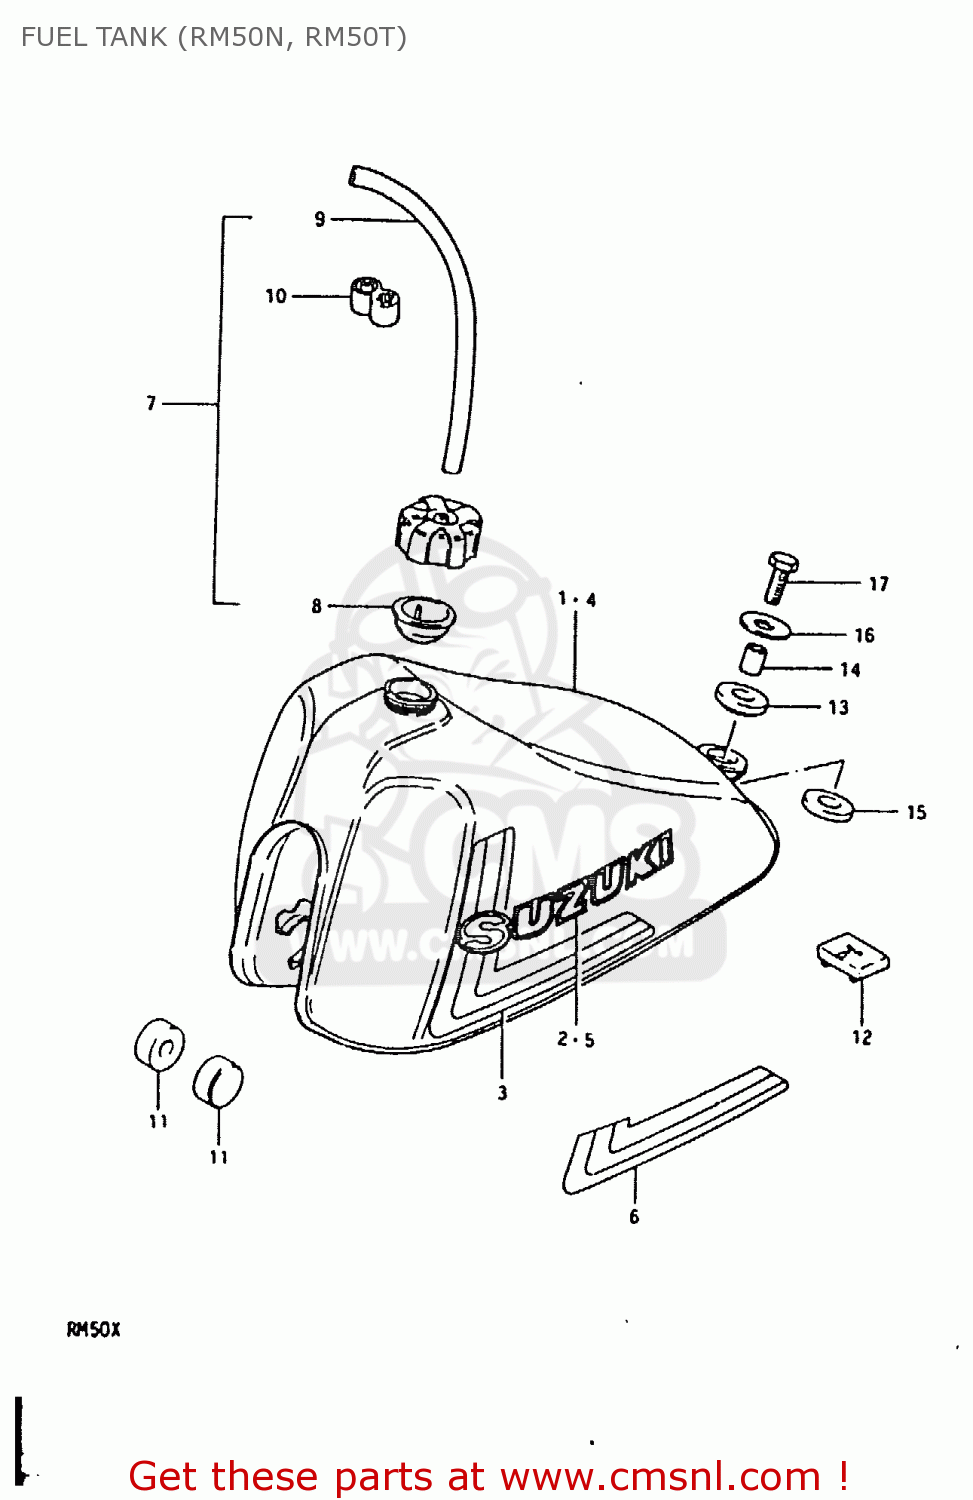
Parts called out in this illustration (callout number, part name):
1	TANK ASSEMBLY,FUEL
2	EMBLEM
3	TAPE SET
4	TANK ASSEMBLY,FUEL
5	EMBLEM
6	TAPE SET,FUEL TANK
7	CAP ASSEMBLY,FUEL TANK
8	GASKET,FUEL TANK CAP
9	HOSE
10	CLAMP,FUEL TANK BREATHER HOSE
11	CUSHION
12	CUSHION,FUEL TANK
13	CUSHION
14	SPACER (8.8X12X13.5)
15	CUSHION
16	BOLT
17	WASHER (8.5X29X1.6)
